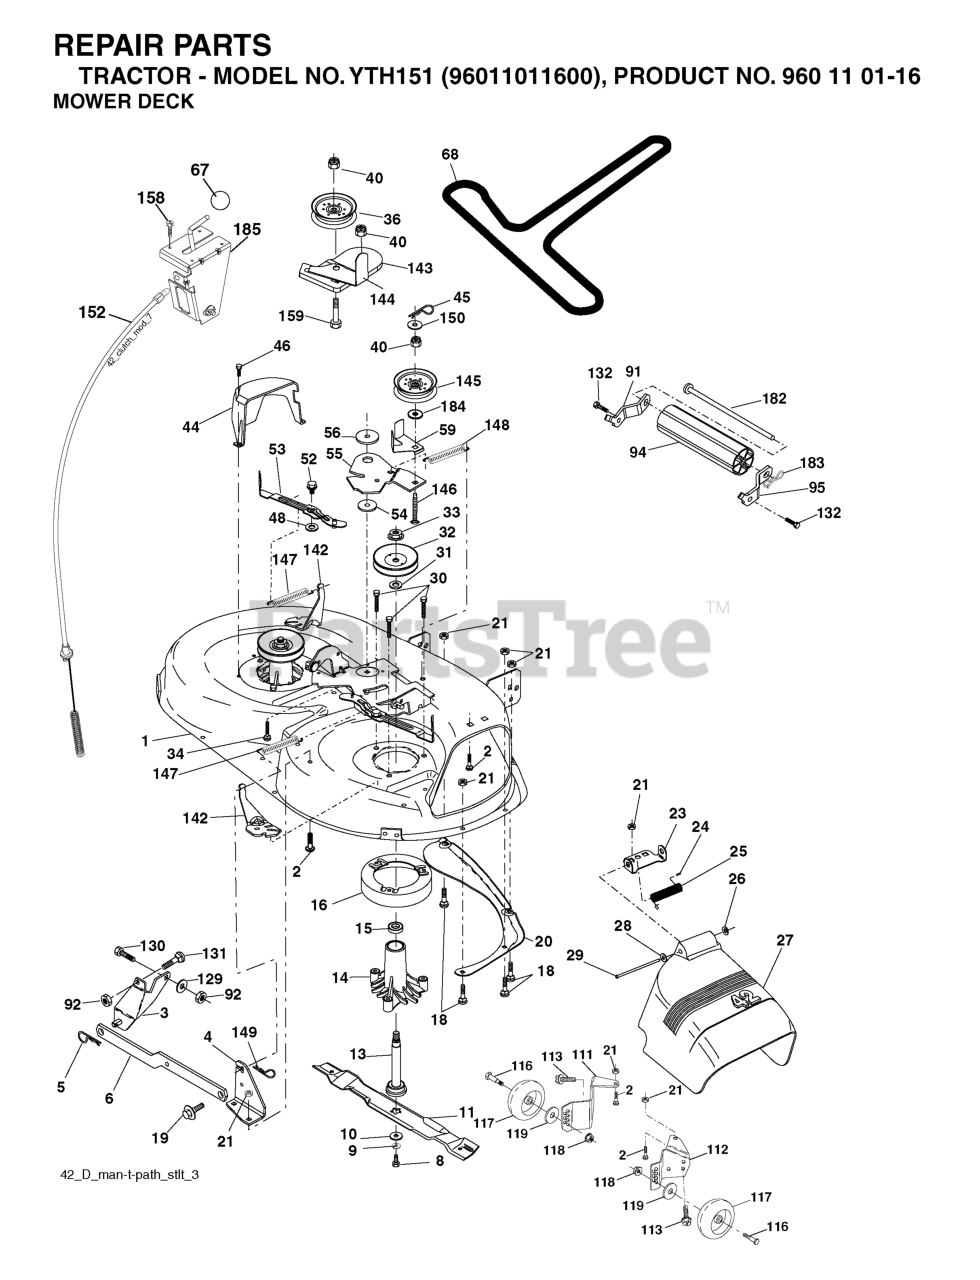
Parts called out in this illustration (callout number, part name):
1	42" DECK KIT
2	RP BOLT 5/16-18 X3/4 ZN/YEL GR
3	BRKT ASM SWAY BAR
4	BRACKET SWAY BAR 42" DECK
5	RETAINER-SPRNG RB
6	BAR SWAY DECK
8	BLADE BOLT
9	LOCKWASHER
10	WASHER.BLADE
11	42" HI-LIFT BLADE
13	SHAFT ASM VENT
14	HOUSING.MANDREL.VENTED (MACHD)
16	STRIPPER.MANDREL.ROUND.BLACK
18	BOLT
19	BOLT SHD 5/16-18
20	BAFFLE.VORTEX
21	LOCKNUT
23	BRKT, DEFL. MOWER
24	CAP-SLEEVE LT
25	SPRING TORSION
26	NUT PUSH M
27	SHIELD DEFLECTOR
28	Washer 11/32 x 5/8 x 16 Ga SD
29	ROD.HINGE
30	SCREW, WASHER HEAD
31	WASHER.SPACER.MANDREL
32	PULLEY/MANDREL
33	NUT.FLANGE.LOCK.TOP
34	BOLT.3/8-16X1.50
36	FLAT IDLER PULLEY
40	NUT LOCK FLG 3/8-16 UNC
44	GUARD MANDREL LH BLACK
45	RETAINER M
46	SCREW.1/4-20X5/8
52	BOLT.SHOULDER.5/16-18
53	ARM BRAKE ASSY
55	ARM IDLER 42" MOWER LT/YT
56	SPACER.RETAINER.MOWER
59	GUARD, BELT
67	KNOB T (3/8 HOLE)
91	BRACKET ASM NOSEROLLER LH
92	NUT
94	NOSE ROLLER
95	BRACKET ASM NOSEROLLER RH
111	BRACKET, WHEEL
112	BRACKET, WHEEL
113	BOLT.5/16HEX.WHS.HD
116	BOLT M
117	WHEEL.GAGE.HALF.SPOKED
118	LOCKNUT
119	WASHER.5/16.FLAT.STE.STD.
129	WASHER
131	BOLT D
132	SCREW, 3/8-16X3/4
142	ARM SPRING BRAKE MOWER
143	BRACKET, ARM IDLER
144	DNO KEEPER.BELT.42".CLUTCH.CBL
145	PULLEY
146	BOLT, CARRIAGE IDLER BLACK
148	IDLER RETURN SPRING
149	SPRING.RETAINER.YELLOW.ZINC
152	CABLE.CLUTCH.42"
158	SCREW
182	ROD ROLLER NOSE STANDARD
183	PIN.COTTER.7/16.BOW TI.
184	WASHER
185	HEAD ASM. CABLE CLUTCH
